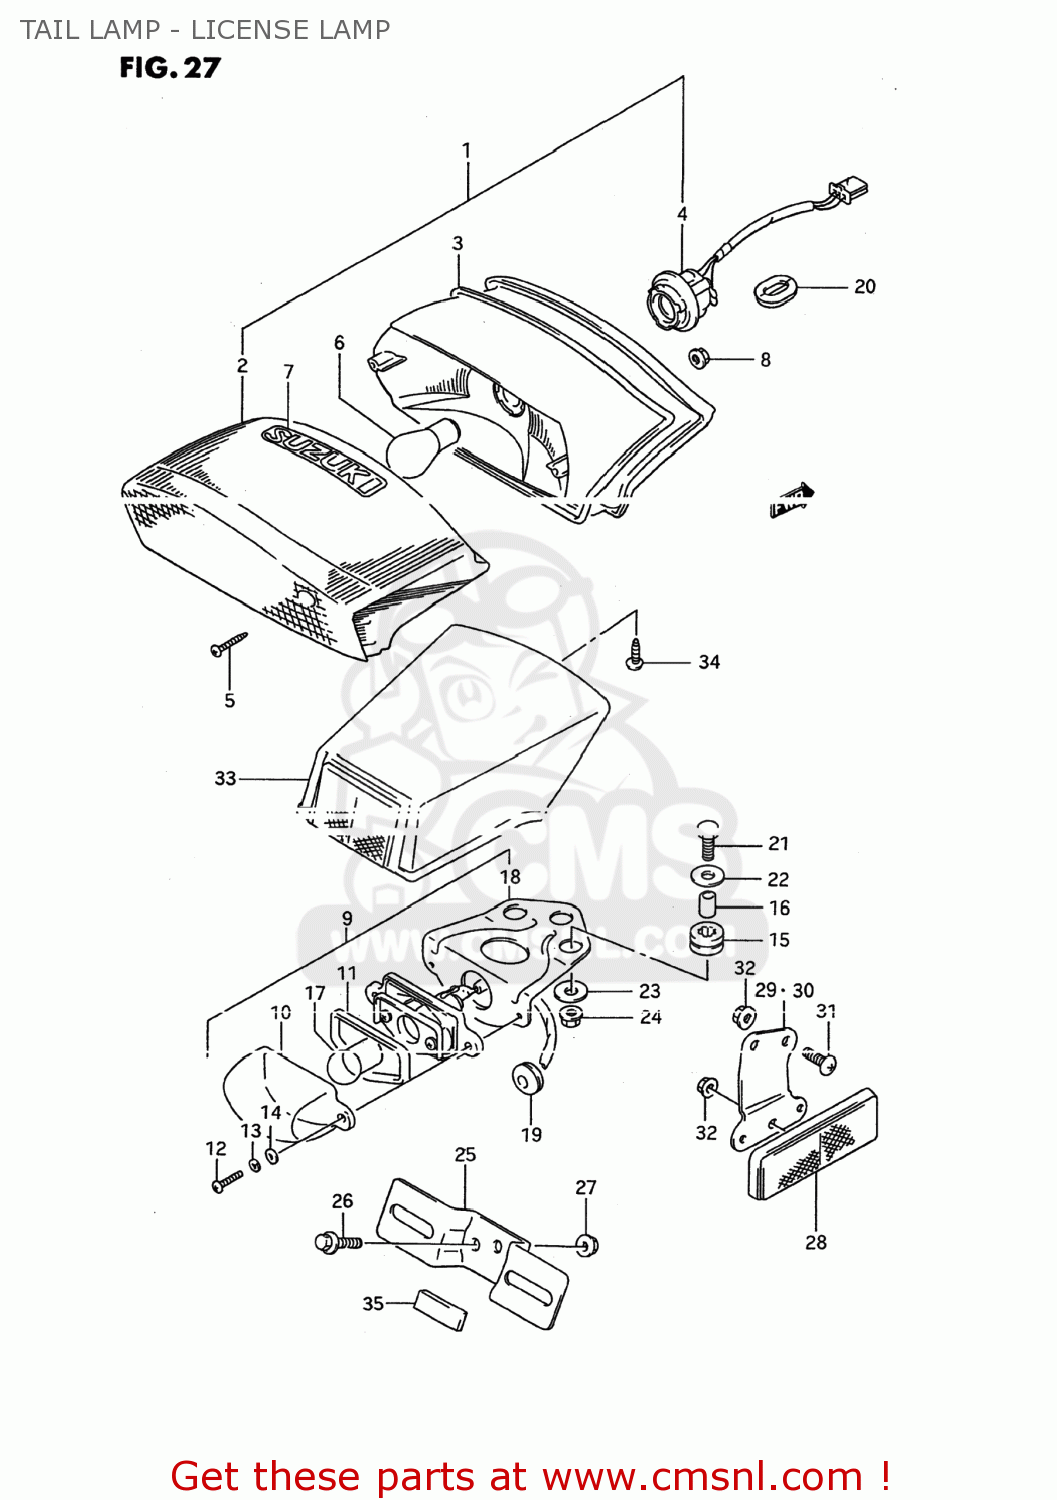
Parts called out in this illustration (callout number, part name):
1	LAMP ASSEMBLY,REAR COMBINATION
2	LENS
3	GASKET (NAS)
4	SOCKET
5	SCREW
6	BULB(12V21/5W,BF141-49642A)
7	EMBLEM
8	NUT
9	LAMP ASSY,LICENSE
10	LENS,LICENSE LAMP
11	GASKET,LICESE LAMP (NAS)
12	SCREW
13	WASHER,LOCK
14	WASHER
15	CUSHION,RR COMBINATION
16	SPACER
17	BULB
18	BRACKET
19	GROMMET
20	GROMMET
21	BOLT
22	WASHER (6.5X20X1.2)
23	WASHER
24	NUT
25	BRACKET,LICENSE PLATE
26	SCREW
27	NUT
28	REFLECTOR ASSY,RR
29	BRACKET
30	BRACKET
31	SCREW 5X12
32	NUT
33	COVER,LICENSE LAMP
34	SCREW
35	PROTECTOR,LICENSE LAMP
